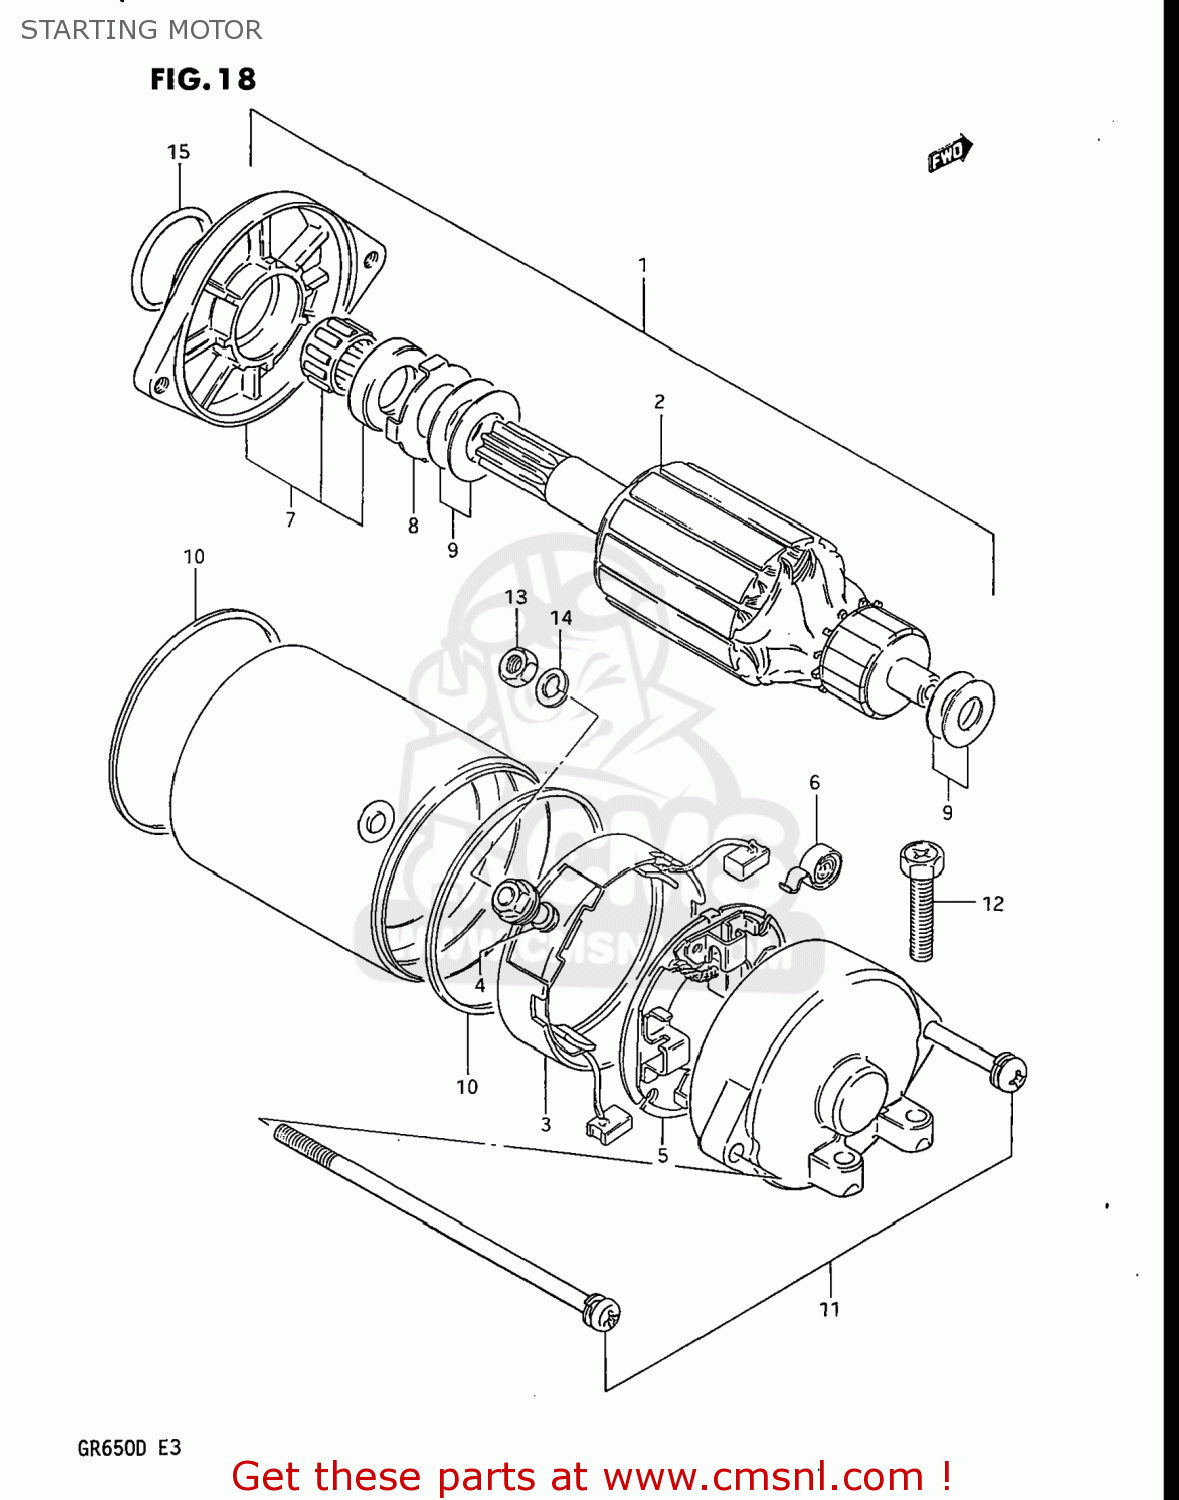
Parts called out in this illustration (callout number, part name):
1	MOTOR ASSEMBLY,STARTING
2	ARMATURE
3	BRUSH TERMINAL SET (+)
4	O RING
5	HOLDER,BRUSH
6	SPRING,BRUSH
7	BRACKET SET,STARTING MOTOR
8	SHIM SET
9	SHIM SET
10	SEAL,RING
11	BOLT
12	SCREW (6X25)
13	NUT 6MM
14	LOCK WASHER
15	O RING(D:3,ID:24.5)
